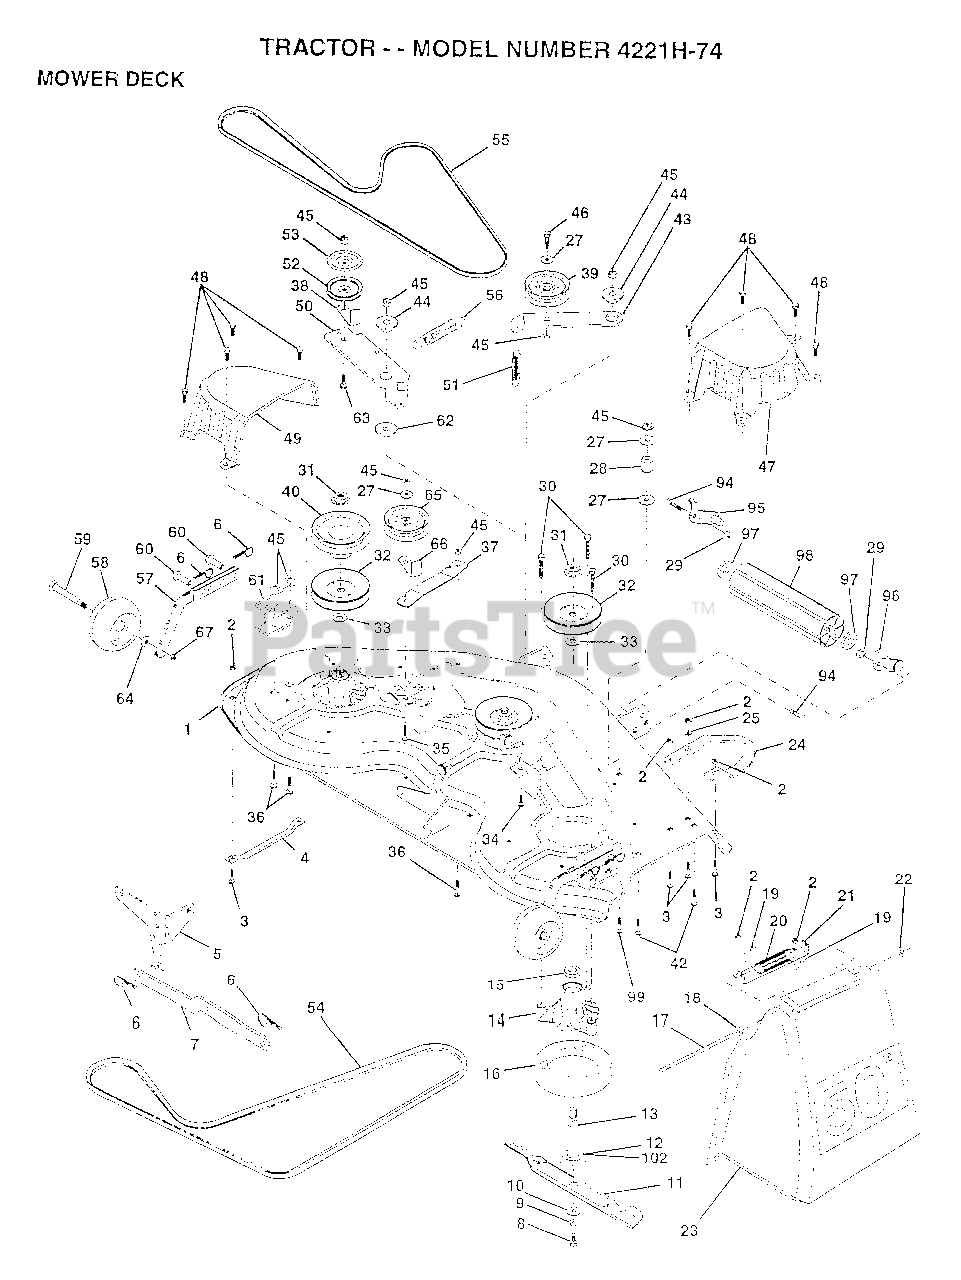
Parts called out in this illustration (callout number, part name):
1	"DECK ASM-50"""
4	RUNNER-LH M
5	BRKT.ASM.SW.44/50
8	BLADE BOLT
10	WASHER.HARD.BLADE
11	"BLADE.50"" HD"
12	BEARING.BALL
13	SHAFT.ASM.W/BRNG
14	HOUSING.MAND.44.V
15	BEARING
16	STRIPPER RND MWR
17	ROD-HINGE T
18	WASHER
19	CAP-SLEEVE LT
20	SPRING TORSION
21	BRKT DEFLECTOR
22	NUT PUSH M
23	DEFLECTOR
24	"RUNNER RH 50"" DK"
25	WASHER M
27	WASHER
29	NUT
32	PULLEY.MANDREL.42
33	WASHER
34	BOLT.3/8-14X1.25
35	BOLT
36	BOLT D
37	STIFFENER.ARM.IDL
38	"KEEPER-BELT,IDLER"
39	FLAT IDLER PULLEY
40	"PULLEY.DRIVEN.44"""
42	BOLT
43	"ARM.IDLER.SEC.44"""
44	SPACER RETAINER
47	"COVER.MAND.RH.44"""
48	SCREW.1/4-20X5/8
49	COVER.MANDREL.LH
50	ARM.IDLER.PRIMARY
51	"SPRING.SEC.44""VEN"
52	PULLEY.IDLER.VGRO
53	SHIELD.IDLER.44.V
54	BELT V PRIM 50
55	BELT-V.SEC.46.KEL
56	SPRING.EXT.DECK.
57	BAR.ASM.GUAGE.WHL
58	WHEEL.GUAGE.MED.
59	BOLT.SHOULDER
60	PIN.CLEVIS
61	BRACKET.GUAGE.WHL
62	HARDENED WASHER
63	BOLT.3/8-16X1.50
64	WASHER
65	PULLEY IDELR FLAT
66	"KEEPER-BELT,IDLER"
67	LOCKNUT
94	BOLT
97	WASHER
99	BOLT
102	WASHER.FELT.
